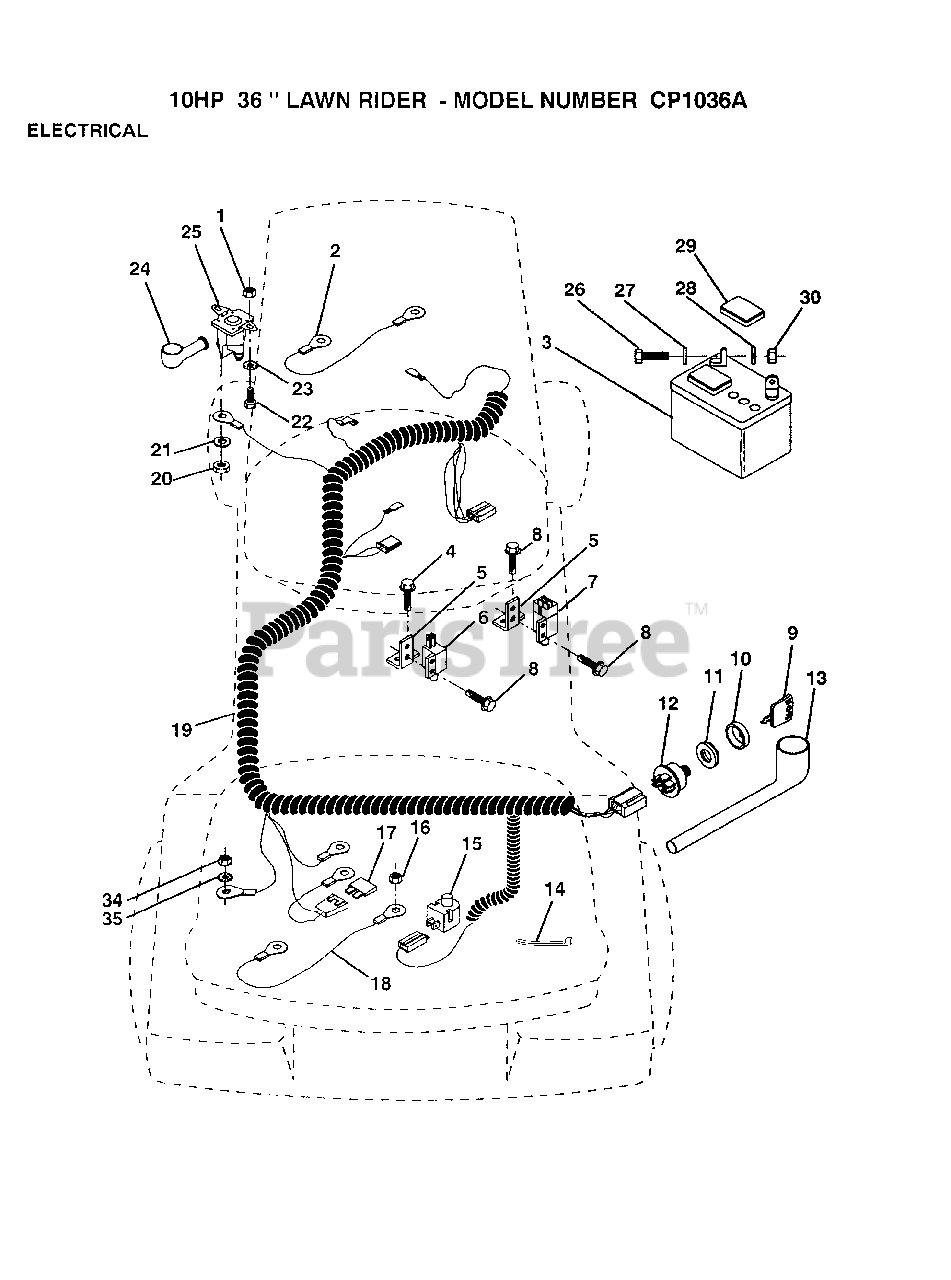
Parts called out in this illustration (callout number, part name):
1	NUT
5	BRACKET LT
6	SWITCH-INTER. GT
7	SWITCH INTERLOCKT
8	SCREW
9	KEY
11	NUT IGNITION
14	WIRE TIE
15	SWITCH SEAT
17	FUSE HYT
18	CABLE ASSY
19	"HARNESS,IGNITION"
20	NUT
22	BOLT
26	BOLT LT
27	WASHER
28	LOCKWASHER
29	"CAP,BATTERY "
34	NUT
35	LOCKWASHER
